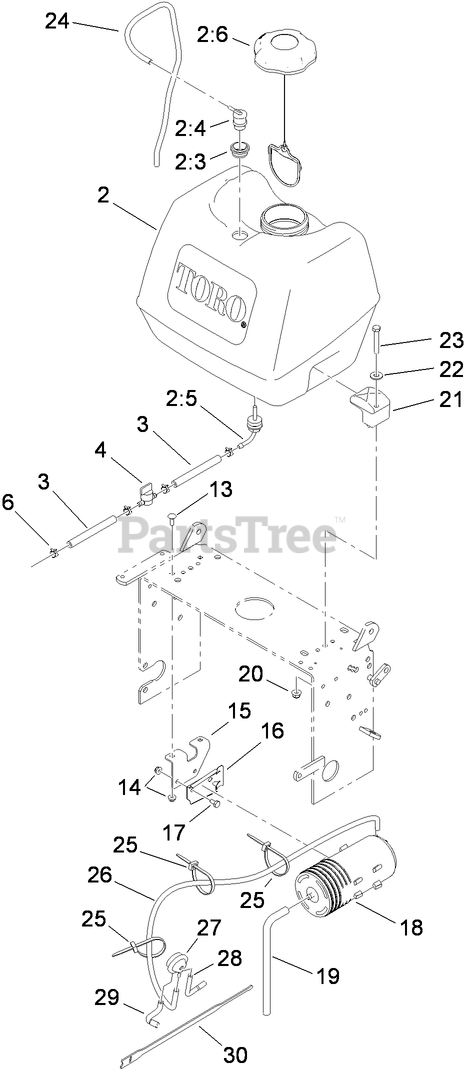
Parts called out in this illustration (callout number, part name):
2	FUEL TANK ASM
2:3	GROMMET-VALVE, ROLL-OVER
2:4	VALVE-ROLLOVER
2:5	FITTING-FUEL, BULKHEAD
2:6	CAP-FUEL, RATCHETING
3	HOSE-FUEL
4	VALVE-FUEL
6	CLAMP-HOSE
13	BOLT-CARR
14	NUT-HF
15	BRACKET-CANISTER, CARBON
16	BRACKET-CANISTER, CARBON
17	SCREW-HH
18	CANISTER-CARBON, 800CC
19	HOSE-VENT, CANISTER
20	NUT-HF, NI
22	WASHER-FLAT
23	SCREW-HH
24	HOSE-VENT
25	TIE-CABLE
26	HOSE-VENT, FORMED
27	VALVE-CONTROL, VACUUM
28	HOSE-VENT, FORMED
29	HOSE-VENT, FORMED
30	STRAP-VELCRO, CABLE TIE
